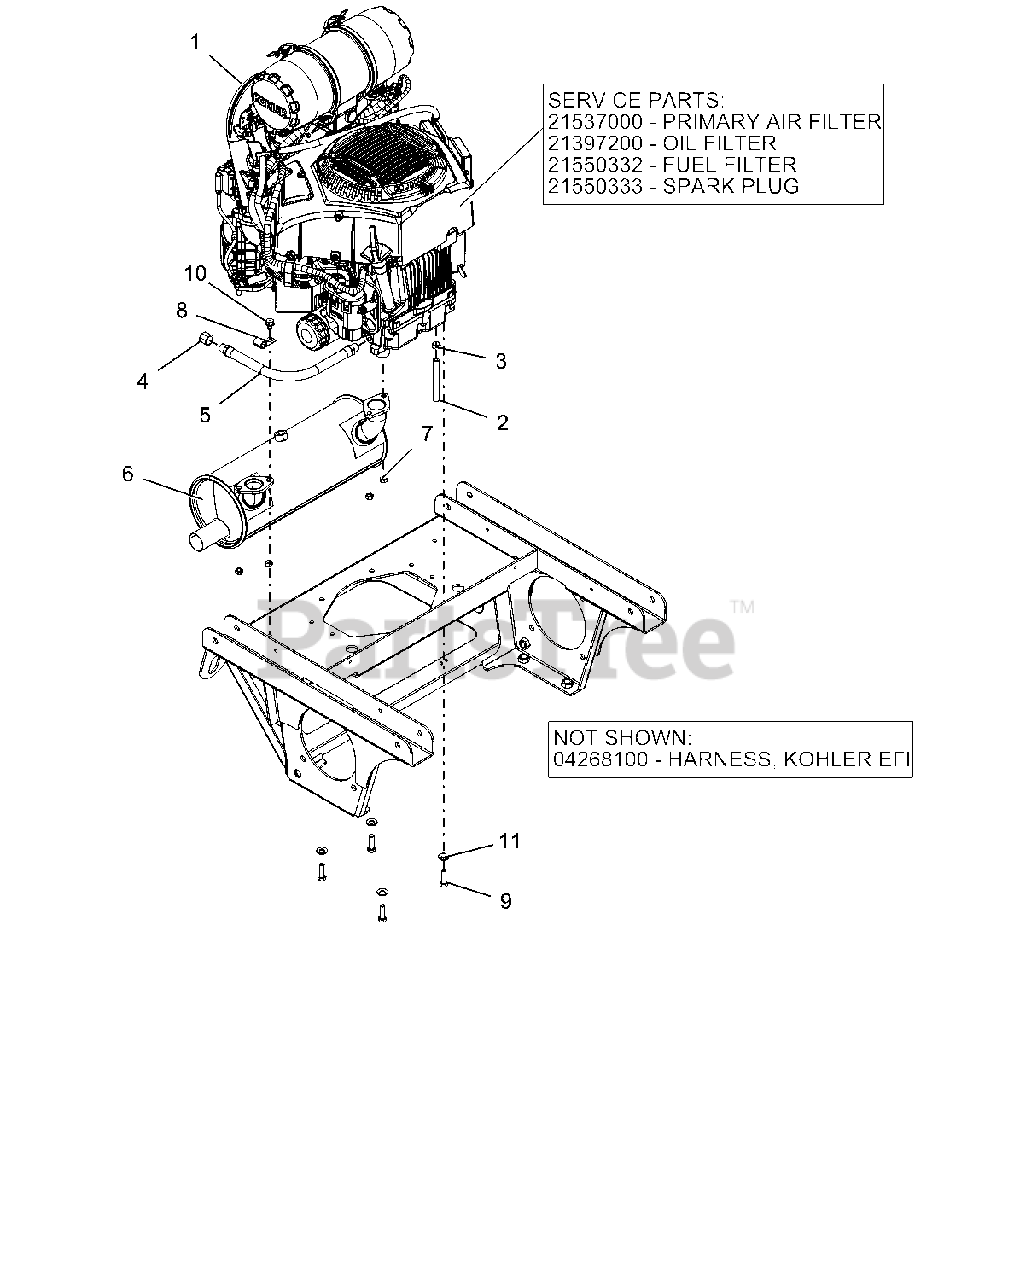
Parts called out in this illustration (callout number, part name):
1	PRIMARY AIR FILTER
1	OIL FILTER
1	FUEL FILTER
1	SPARK PLUG
1	ENGINE, KOHLER EFI
2	.25 LOW-PERM GAS HOSE 19.0" LG - VALVE TO ENGINE
3	CLAMP, FUEL LINE
4	PIPE, CAP 3/8 NPT FEMALE
5	HOSE, HYD .38-11-OK M6N0-M6N0
6	MUFFLER, KOHLER EFI
7	NUT-LK-TOP M8-1.25 YWZC
9	BLT-HEX .38-16X1.25 GR5 YWZC NYTORQ
10	SCR-TAP .38-16X.50 HWH TR YWZ
11	WSHR, 3/8" SPRING DISC
